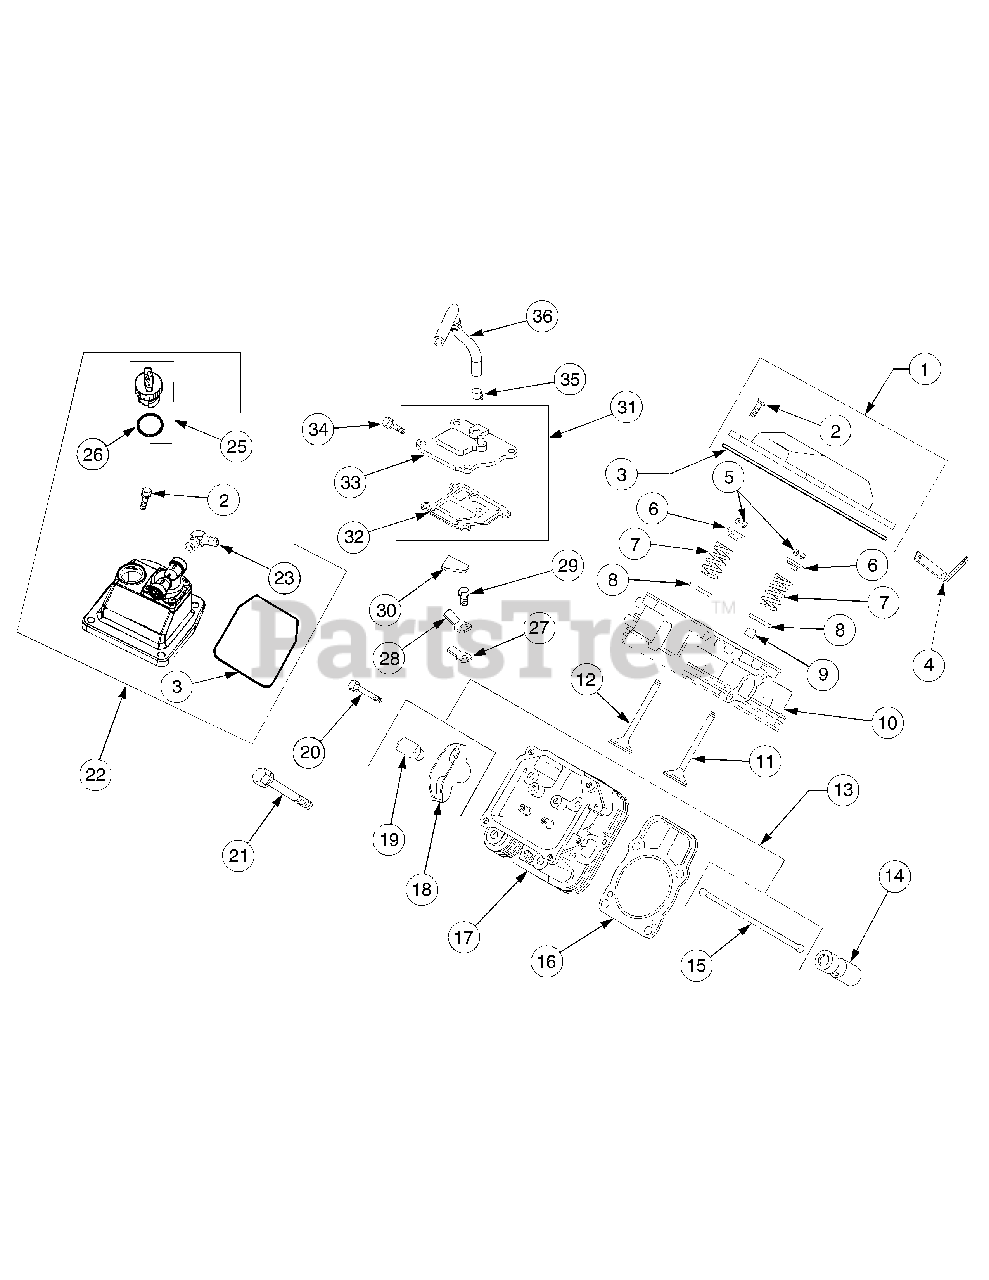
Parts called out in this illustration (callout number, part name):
1	Kit, Valve Cover (Includes 2-3)
2	Screw, Hex Flng, M6 x1.0 x 30
3	O-Ring, Valve Cover
4	Strap, Lifting
5	Kit, Retainer
6	Cap, Valve Spring
7	Spring, Valve
8	Retainer, Spring
9	Seal, Valve Stem
10	Head Assembly, #1 Cylinder
11	Valve, Intake Std
11	Valve, Intake, .25mm
12	Valve, Exhaust Std
12	Valve, Exhaust, .25mm
13	Kit, Valve Train (Incl. 15,18,19)
14	Lifter, Valve
16	Kit, Cyl. Hd. Gasket (Includes 21)
17	Head Assembly, #2 Cylinder
19	Pivot, Rocker Arm
20	Screw, Hex Flng, M6 x 1.0 x 34
21	Screw, Hex Flng, M10 x 1.5 x 90
22	Kit, Fuel Pump Valve Cover
23	Fitting, 90°
25	Cap Assembly, Oil Fill (Incl. 26)
26	O-Ring
27	Reed, Breather
28	Retainer, Breather Reed
29	Screw, Hex Flng, M5 x 0.8 x 10
30	Filter, Breather
31	Kit, Breather (Includes 32-34)
32	Gasket, Breather
33	Cover, Breather
34	Screw, Hex Flng M6 x 1.0 x 20
35	Clamp, Breather
36	Hose, Breather
